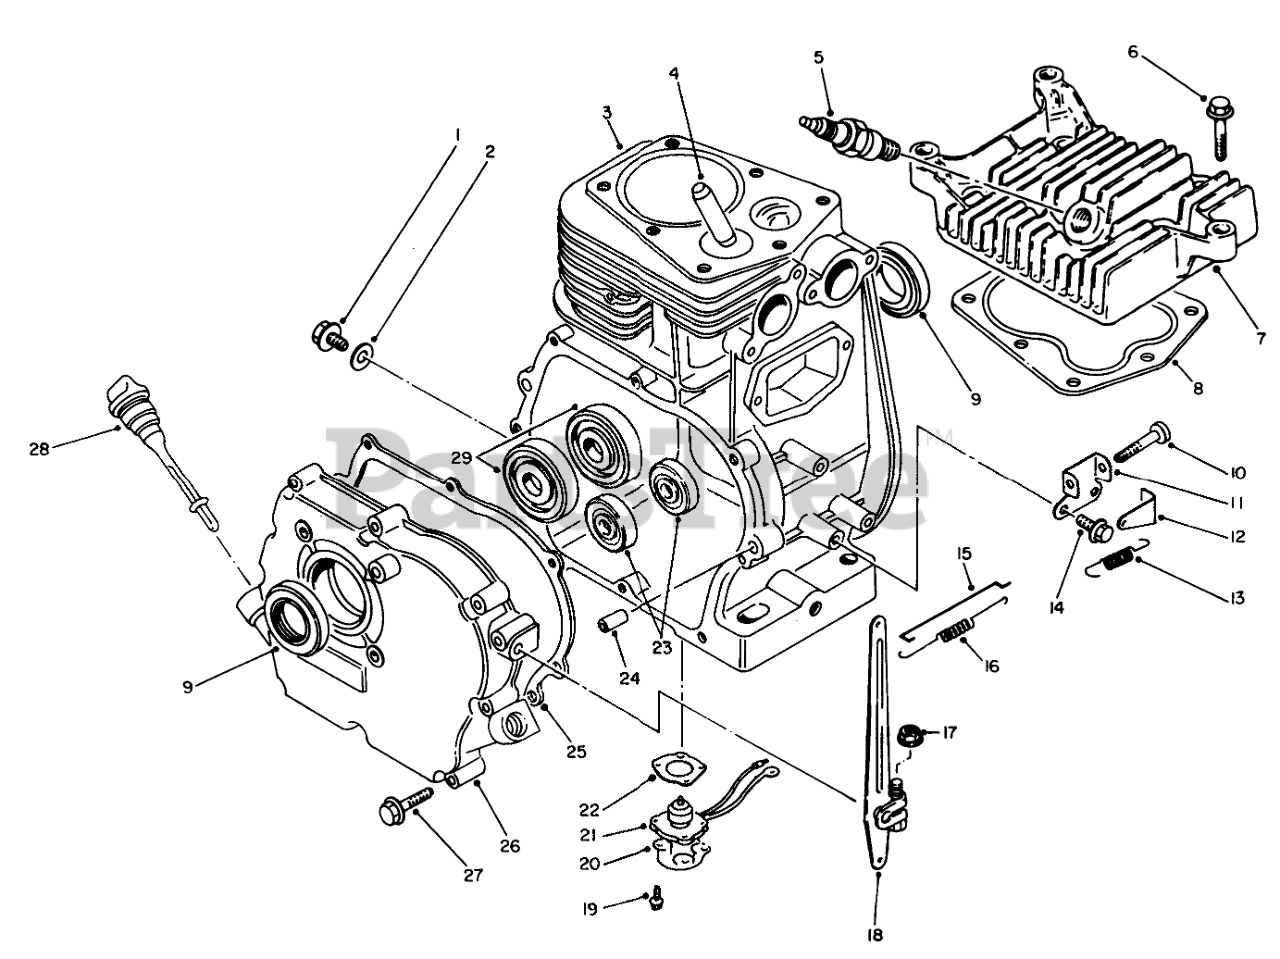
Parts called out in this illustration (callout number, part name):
1	Drain Plug
2	GASKET
3	Cylinder
4	VALVE GUIDE
5	SPARK PLUG
7	Cylinder Head
8	GASKET
9	OIL SEAL
11	Bracket
13	SPRING
15	Rod-Carburetor
16	SPRING
18	CONTROL LEVER
20	Plate
21	SENSOR
22	GASKET
23	Bearing
25	Gasket
26	Cover
28	Gasket
29	Screw
